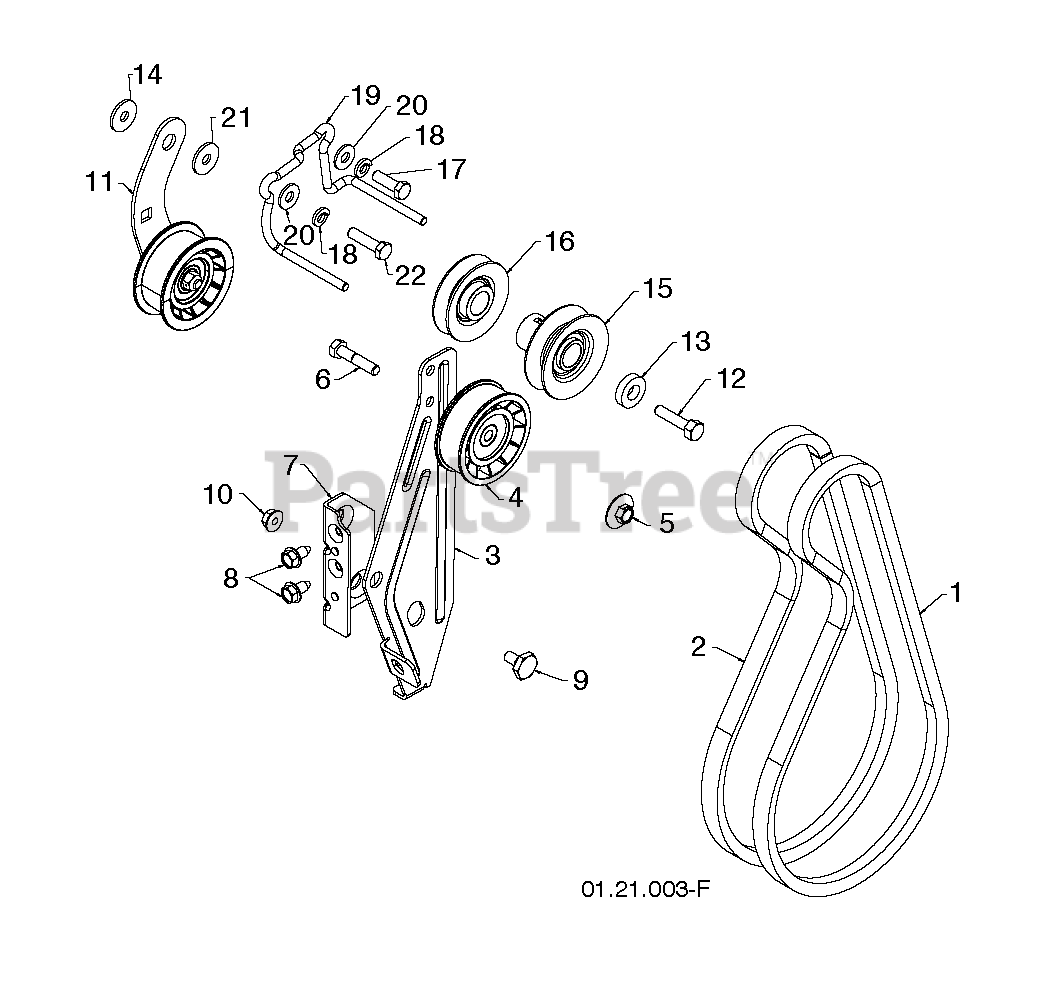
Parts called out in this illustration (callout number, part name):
1	BELT.V.IMPELLER
2	V-BELT TRACTION 34.25
3	ARM.IDLER BRAKE.CLEAR.ZINC
4	PULLEY.W/SPACER.2.75
5	NUT.FLANGE.HEX.5/16X18.BLACK
6	HEX BOLT
7	BRACKET.IDLER.PIVOT.ZINC
8	BOLT.5/16HEX.WHS.HD
9	BOLT.SHOULDER.1/2X12
10	NUT.LOCK.5/16-18
11	ARM.ASM.TRACTION.IDLER.SNOW
12	SCREW, HEX HD 3/8-24 X 1-3/8
13	WASHER, FLAT 3/8
14	BUSHING, IDLER PIVOT
15	PULLEY.IMPELER.
16	PULLEY.ENG.TRACTION
18	LOCKWASHER
19	RB GUIDE.BELT.CHAIN.LS.SNOW
20	WASHER.20X8.5
21	STEEL WASHER
22	CAPSCREW.HEXHD.5/16X1.25.
